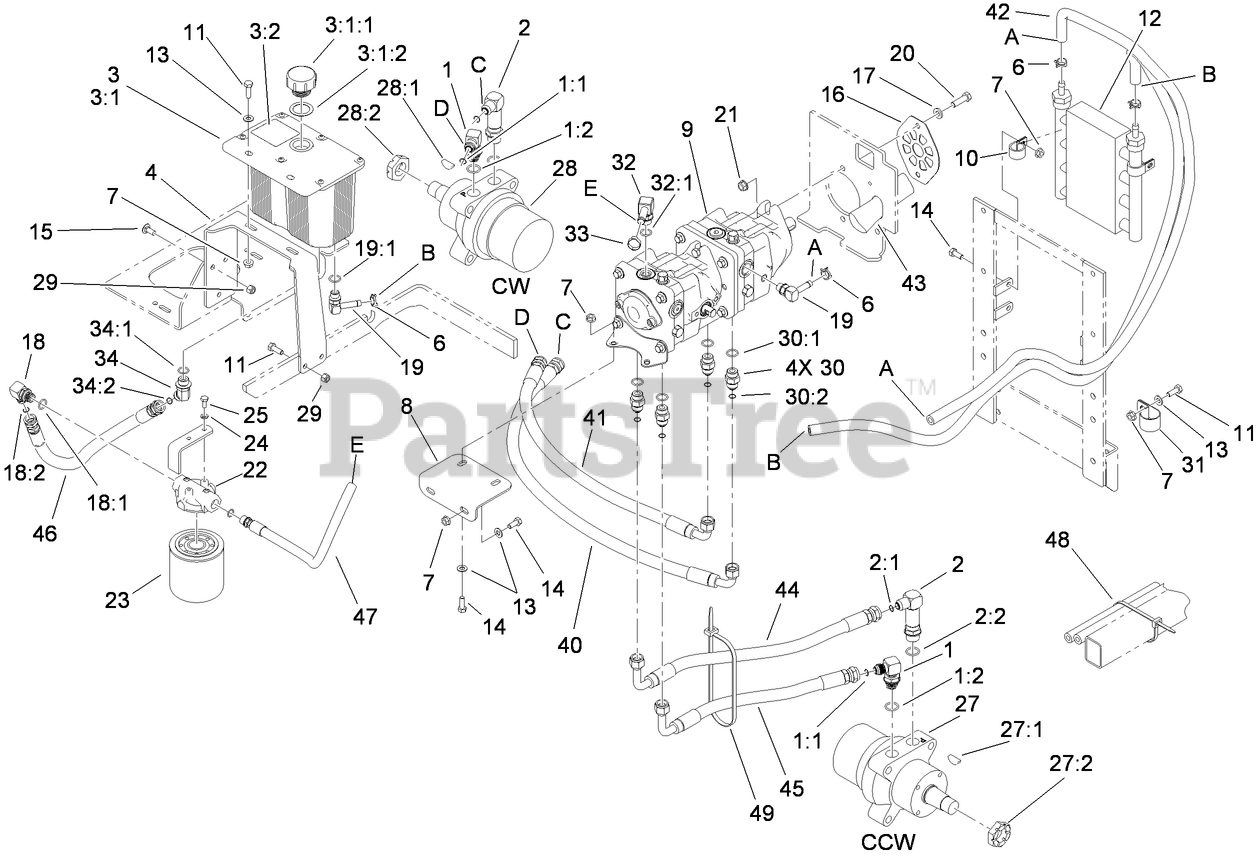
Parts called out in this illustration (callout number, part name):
1	FITTING-HYD, 90 DEG
1:1	O-Ring
1:2	O-RING
2	FITTING-ELBOW-90
2:1	O-Ring
2:2	O-RING
3	HYDRAULIC TANK ASM
3:1	TANK-HYDRAULIC
3:1:1	CAP-RESERVOIR, HYD
3:1:2	GASKET-CAP
3:2	DECAL-TANK, HYD
4	BRACKET-TANK, HYDRAULIC
6	CLAMP-HOSE
7	NUT-HF
8	BRACKET-PUMP, FRONT
9	TANDEM PUMP ASM
10	R-CLAMP
11	SCREW-HH
12	COOLER-OIL, HYDRO
13	WASHER-PLAIN
14	SCREW-HH
15	SCREW-CARR
16	PLATE-SHIELD, PUMP
17	WASHER-FLAT
18	FITTING-90 DEG
18:1	O-RING
18:2	O-Ring
19	FITTING-ELBOW, 90
19:1	O-Ring
20	SCREW-HH
21	NUT-HHF, WHIZ
22	HEAD-FILTER
23	CARTRIDGE-FILTER, OIL
24	WASHER-LOCK
25	SCREW-HH
27	HYD MOTOR ASM (CCW)
27:1	KEY-WOODRUFF
27:2	NUT-HH
28	HYD MOTOR ASM (CW)
28:1	KEY-WOODRUFF
28:2	NUT-HH
29	NUT-LOCK, NI
30	FITTING-STRAIGHT
30:1	O-RING
30:2	O-Ring
31	CLAMP-R
32	FITTING-ELBOW, 90 DEG
32:1	O-RING
33	CLAMP-HOSE
34	FITTING-HYD, 45 DEG
34:1	O-RING
34:2	O-Ring
40	HYDRAULIC HOSE ASM
41	HYDRAULIC HOSE ASM
42	HOSE-HYDRAULIC
43	SLEEVE-FABRIC
44	HYDRAULIC HOSE ASM
45	HYDRAULIC HOSE ASM
46	HYDRAULIC HOSE ASM
47	HYDRAULIC HOSE ASM
48	TIE-PLASTIC
49	CABLE TIE-PLASTIC
